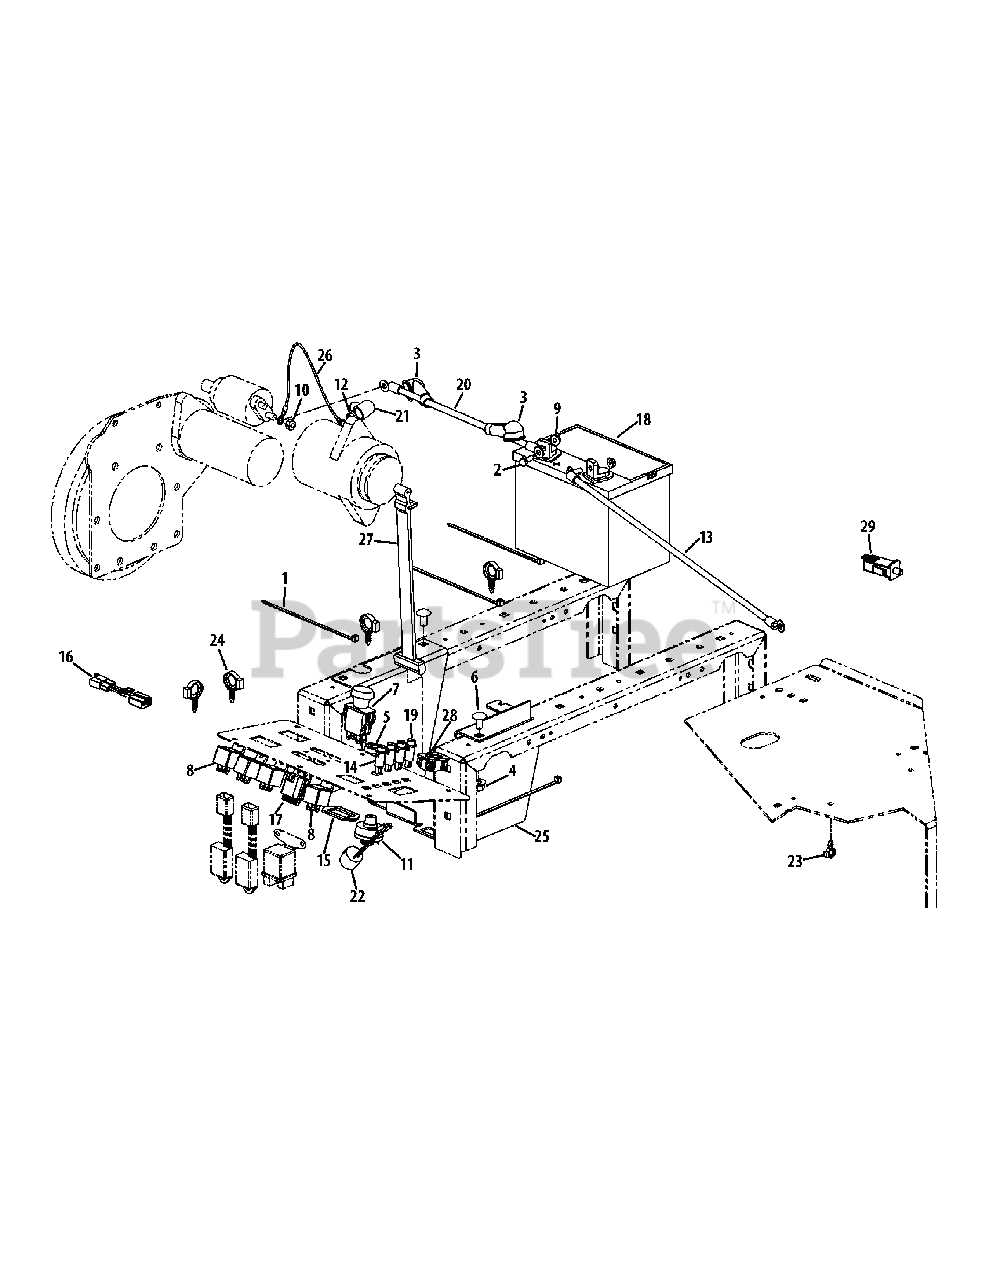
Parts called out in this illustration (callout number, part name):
1	Cable Tie
2	Hex Screw, 1/4-20 x .75
3	Boot Terminal, Red
4	Flange Counter Lock Nut, 3/8-16
5	Nut, 5/8-32 w/ Cap, Ignition
6	Carriage Bolt, 3/8-16 x .75
7	PTO Switch
8	Relay, 12V, 20/30A
9	Flange Top Lock Nut, 1/4-20, GR-F
10	Nut, M8-1.25, GR8.8, Lock
11	Ignition Switch, 6 pin
12	Counter Lock Nut, M6x1, GR5
13	Battery Cable, Black
14	Indicator Light, Red
15	Return Switch PTO Bracket
16	Adapter, Diode, EFI
17	Shut Down Interlock, Time Delay
18	Battery, 375 CCA, Dry
19	Indicator Light, 12v Amber
20	Battery Cable, Red 42"
21	Boot Terminal, .675 x 1.65 Red
22	Alarm, High Temperature
23	Clip, Electrical, 3/8"
24	Clip, Electrical, 5/8"
27	Battery Strap, Retainer
29	Switch, Interlock
